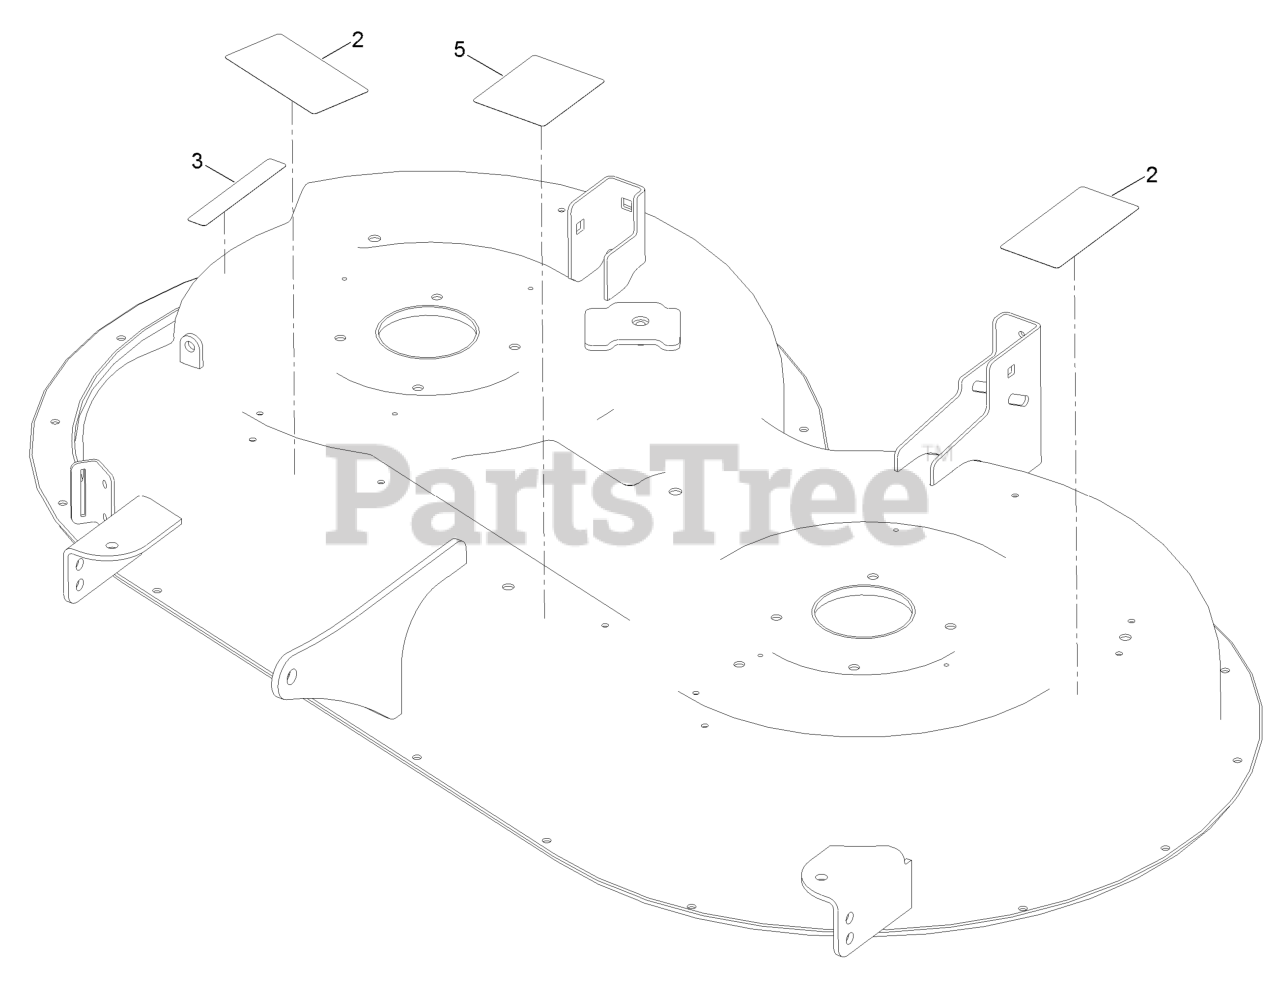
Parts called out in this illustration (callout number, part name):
2	Decal-Danger, Deck
3	Decal-Danger
5	Decal-Routing, Belt
